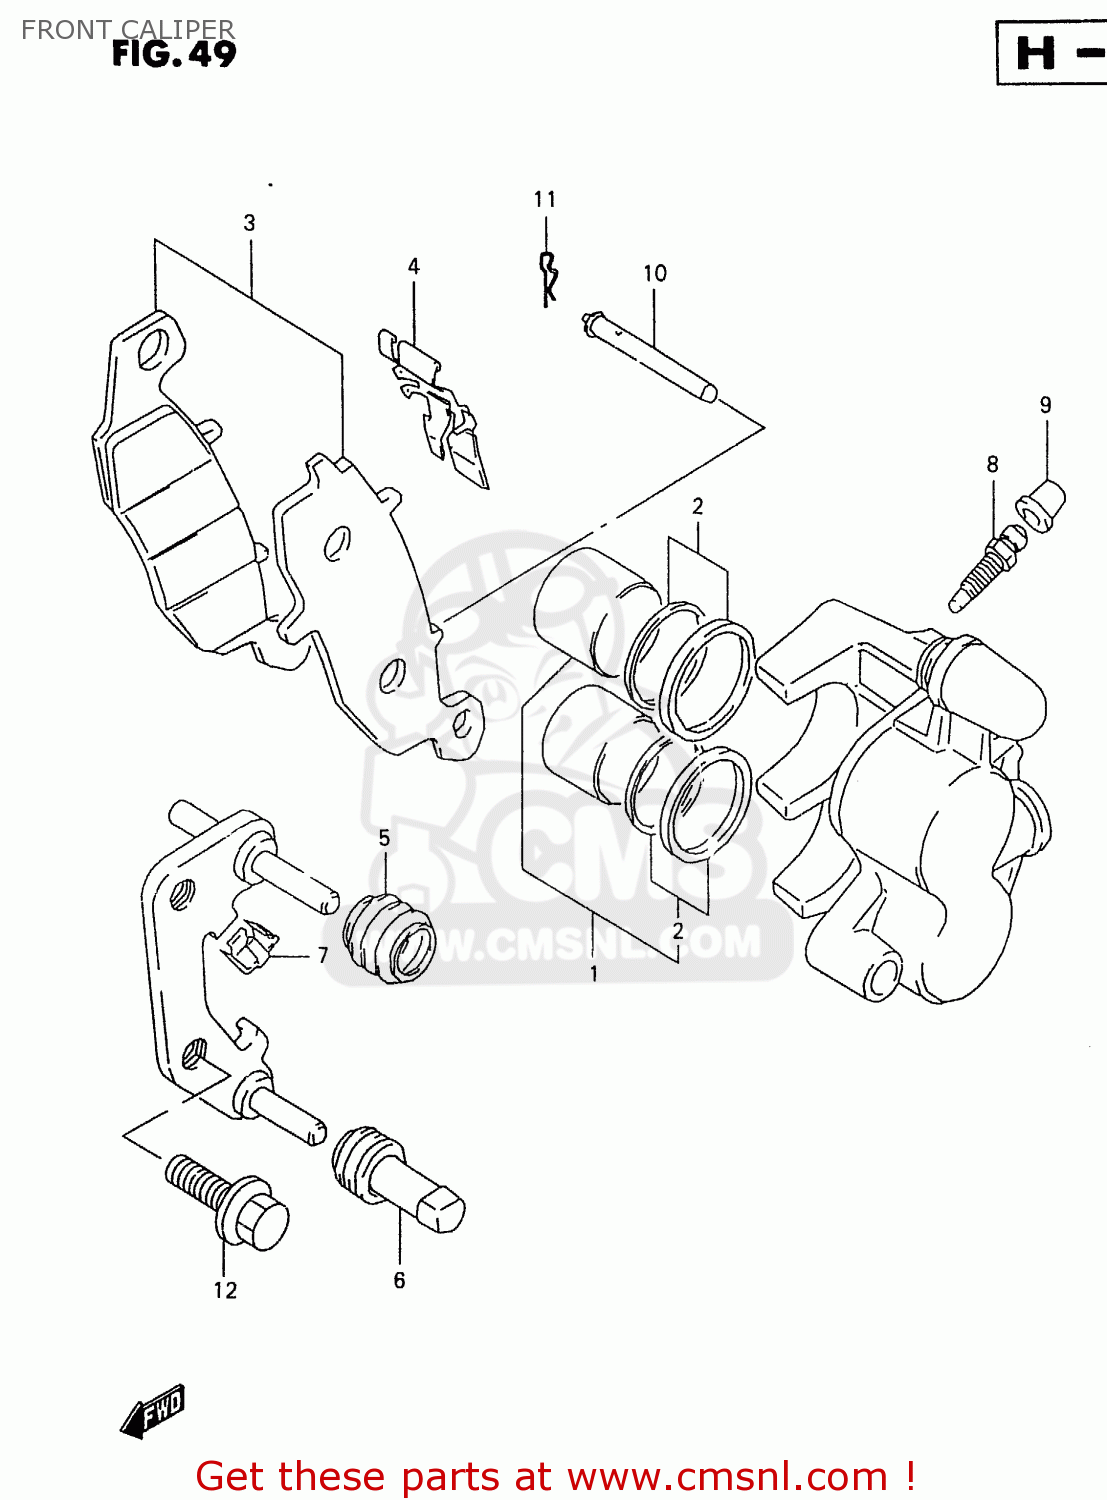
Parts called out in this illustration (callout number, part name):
1	PISTON SET
2	SEAL SET,PISTON
3	PAD SET,R (NAS)
4	SPRING,PAD,R
5	BOOT,AXLE
6	INSULATOR,AXLE
7	GUIDE,PAD
8	BLEEDER
9	CAP,BLEEDER PLUG
10	PIN,PAD
11	CLIP,PAD PIN
12	BOLT
